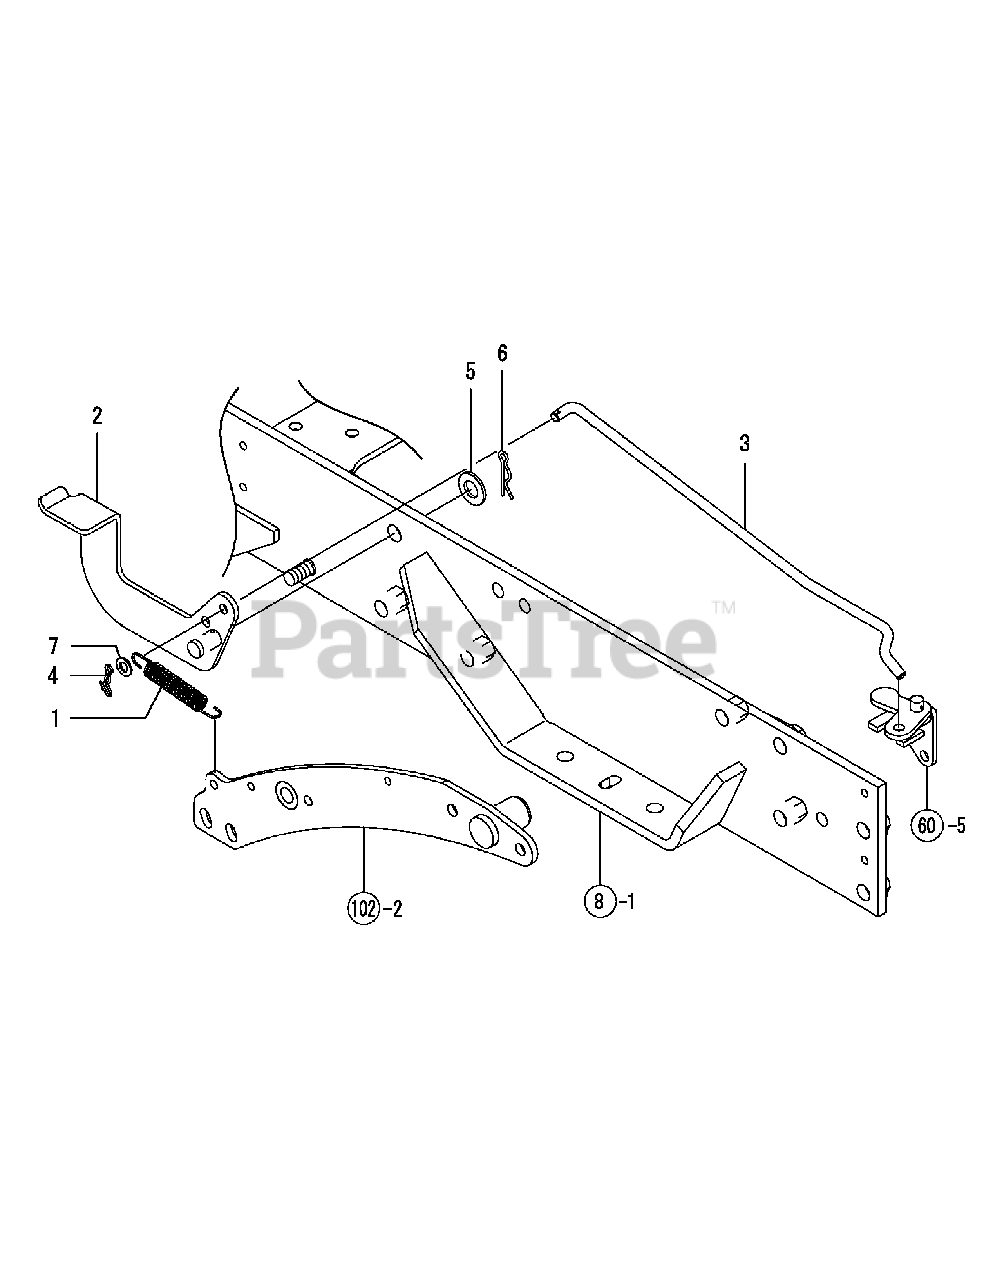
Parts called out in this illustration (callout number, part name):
1	SPRING, RETURN
2	PEDAL CMP, DIFF.
4	PIN 8, COME-OFF SNAP
5	WASHER 14, POLISHED
7	WASHER 8, POLISHED
